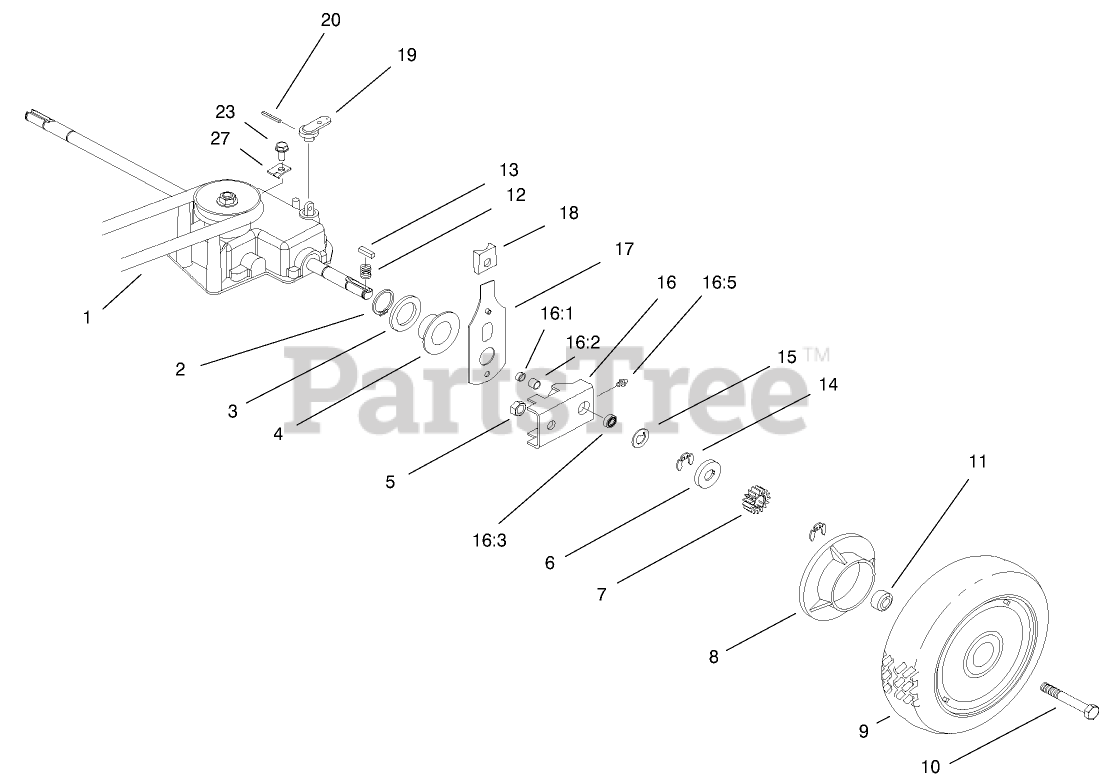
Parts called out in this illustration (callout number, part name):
1	V-BELT
2	RING-RETAINING
3	WASHER
4	CAP-END
5	NUT-LOCK, CONE
6	WASHER-THRUST, OUTER
7	GEAR-PINION
8	COVER-WHEEL
10	SCREW-HH
11	SPACER-COVER, WHEEL
12	SPRING-COMPRESSION
14	RING-RETAINING
15	WASHER-THRUST, OUTER
16	PIVOT ARM ASM
16:1	SEAL-OIL
16:3	BEARING-WHEEL
17	REAR SPRING ARM ASM
18	KNOB-ARM
19	LEVER-SHIFT
20	PIN-SPRING
23	SCREW-HWHTF
27	CLAMP-CABLE
